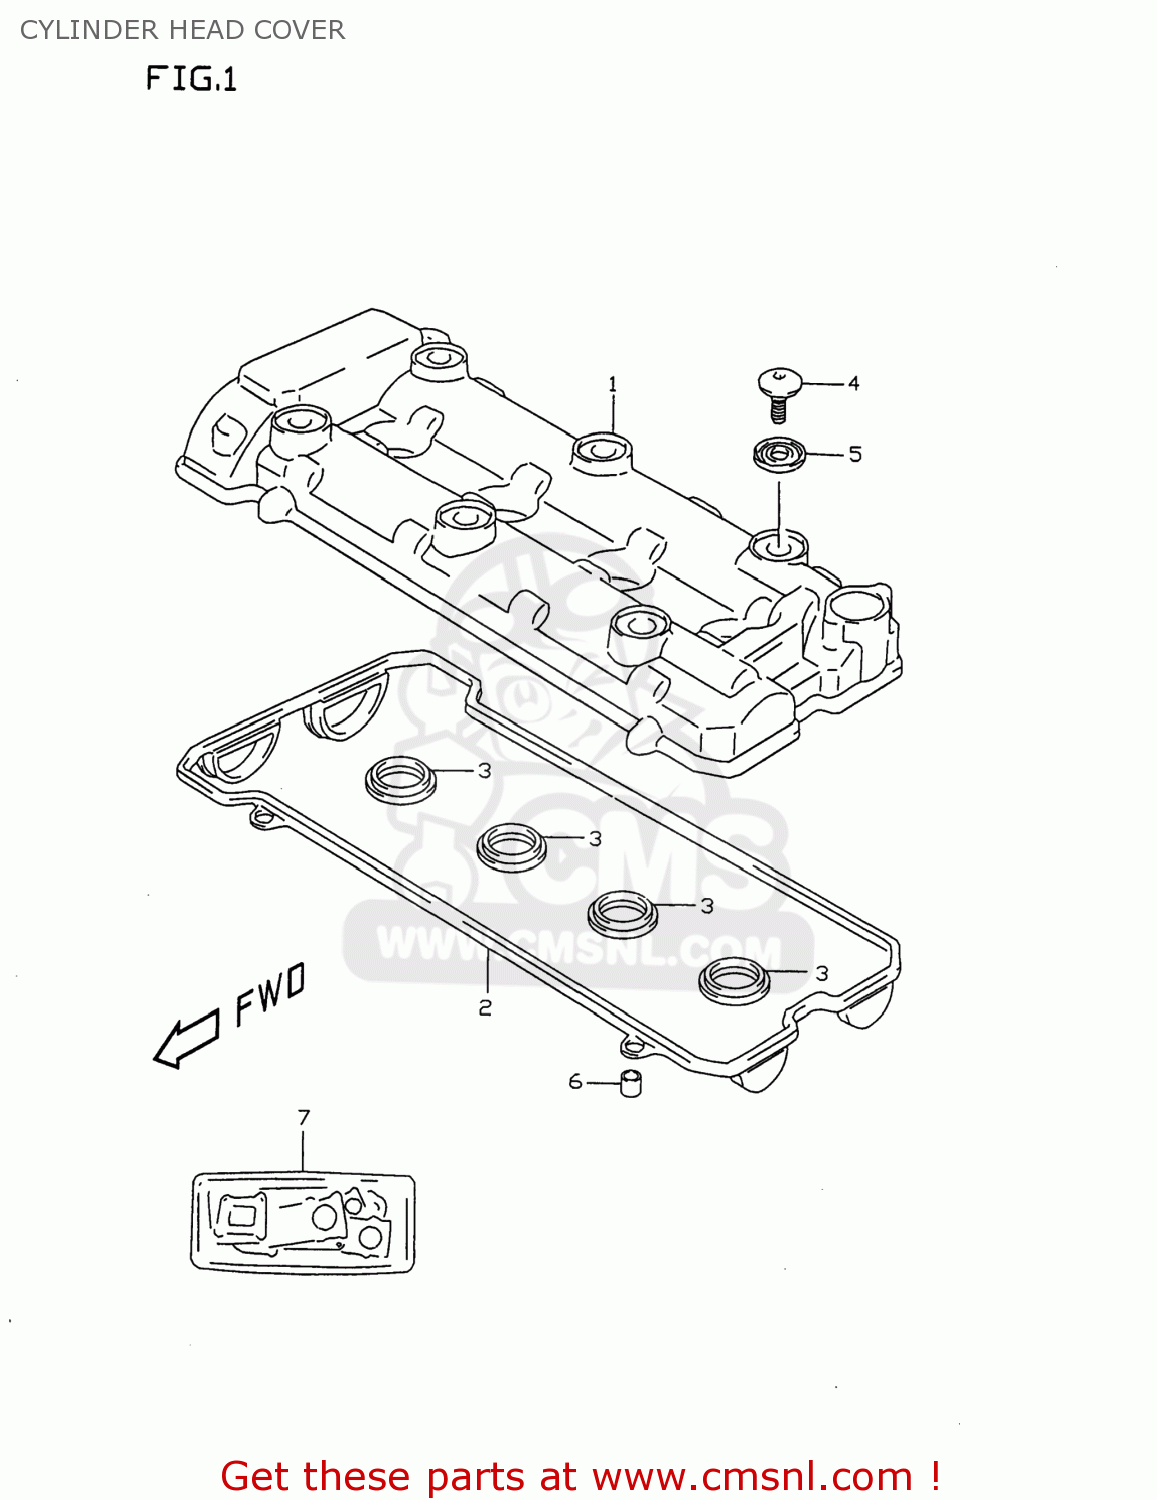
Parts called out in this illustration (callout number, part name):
1	COVER,CYLINDER HEAD
2	GASKET,CYL HEAD COVER NO.1
3	GASKET,CYL HEAD COVER NO.2
4	BOLT(7X17.5)
5	WASHER(10.6X25.5X2.3)
6	PIN(6.2X8X11)
7	GASKET SET (NAS)
